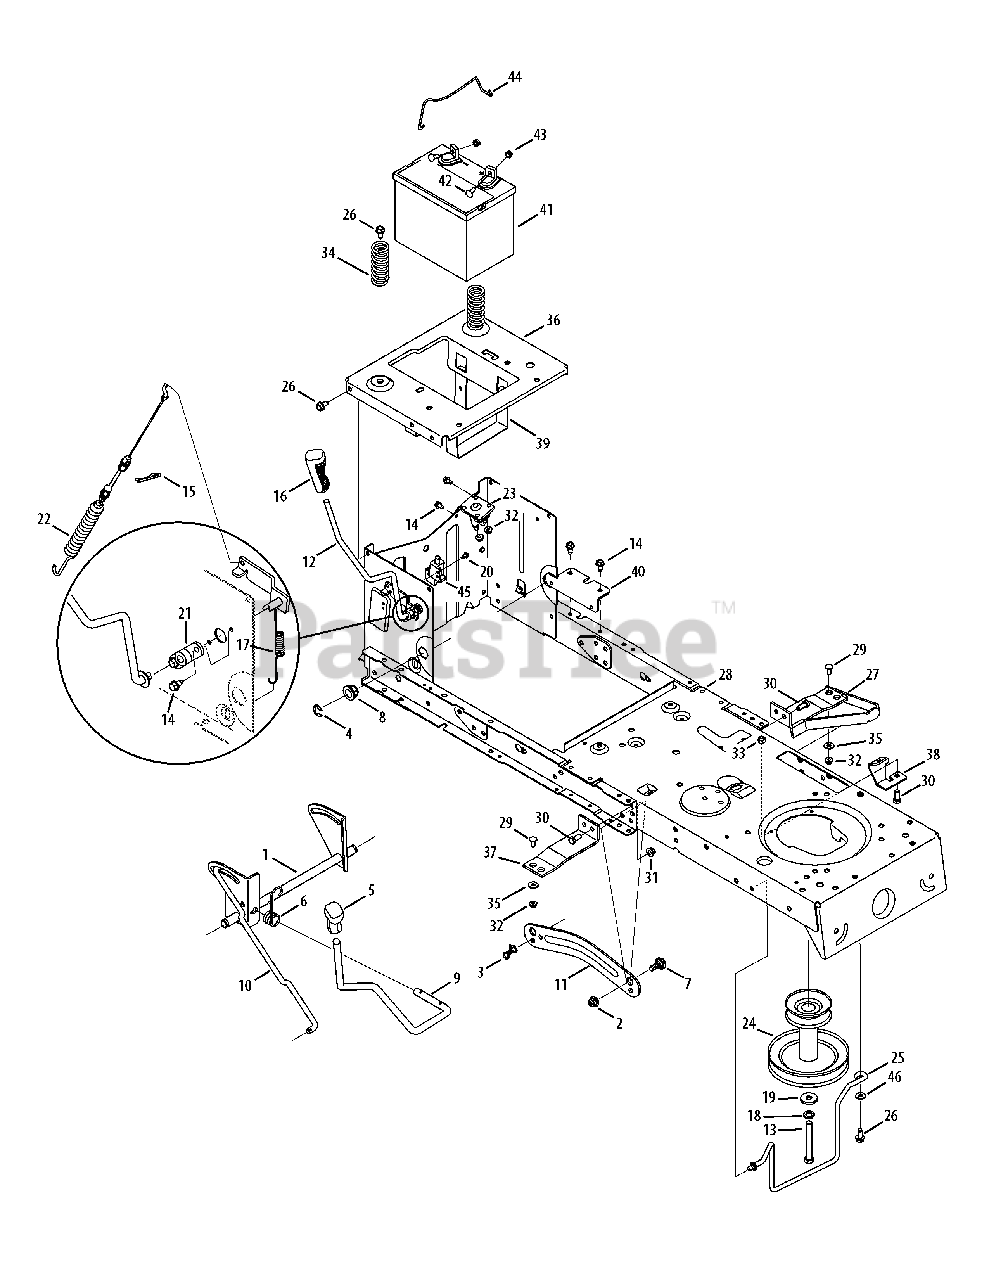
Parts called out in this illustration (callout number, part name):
1	Shaft, Lift
2	Nut, Hex Flange Insert Lock, 3/8-16
3	Bow-Tie Pin, 91, RH
4	E-ring, .625 Shaft
5	Grip, Handle
6	Spring, Lift Handle Torsion
7	Bolt, Shoulder, .625 x .175:3/8-16
8	Bearing, Hex Flange
9	Handle, Lift
10	Lift Rod, 13.68
11	Arm, Deck Lift RH
11	Arm, Deck Lift LH
12	PTO Handle Assembly
13	Screw, Hx. Hd., 7/16-20 x 3.25
14	Screw, Hd. Tapp, 1/4-20 x .5
15	Click Pin
16	Handle Grip
17	PTO Spring, Extension
18	Washer, Flat, 7/16
19	Washer, Flat, .450 x .250 x .164
20	Shoulder Screw, #10-32 x .500
21	PTO Bearing
22	Deck Engagement Cable
23	12v. Solenoid
24	Engagement Pulley
25	Belt Keeper Rod Assembly
26	Screw, Hd. Tapp, 5/16-18 x .75
27	Support Bracket Assembly
28	Rider Frame Assembly
29	Carriage Screw, 1/4-20 x .62
30	Screw, Hx. Hd., 5/16-18 x .75
31	Nut, Hex Flange Insert Lock, 5/16-18
32	Nut, Hex Flange Insert Lock, 1/4-20
33	Hexlock Nut, 5/16-18
34	Spring, Compress., 1.28 x 3.125
35	Flat Washer, .28 x .74 x .063
36	Seat Bracket Frame
37	Running Board Bracket
38	Frame Support Bracket
39	Battery Bracket
40	Frame Brace Bracket
41	Battery
42	Screw, Shoulder, .250 x .150
43	Nut, Sems, 1/4-20
44	Battery Rod
45	Interlock Switch
46	Flat Washer, .406 x .875 x .059
